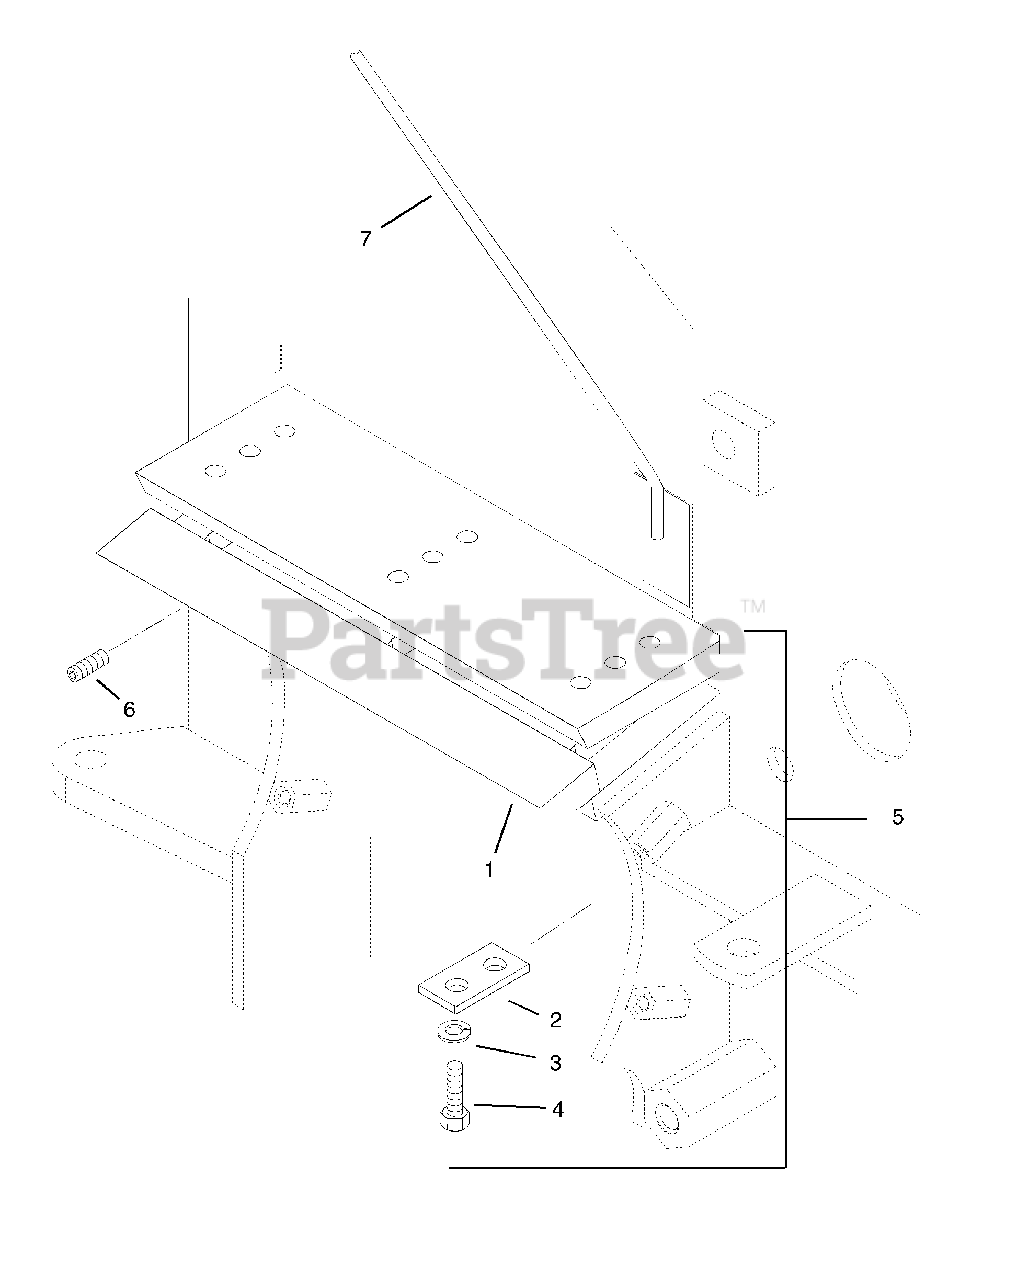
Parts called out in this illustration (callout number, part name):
2	Double Hole Washer
3	Washer-Locking .38 X .094
4	Bolt-Hex .38-24 x 1.25 Grade 8
5	Bed Knife Kit
6	Screw-Set-Socket Head .38-16 X .75
7	Knife Gauge .030
